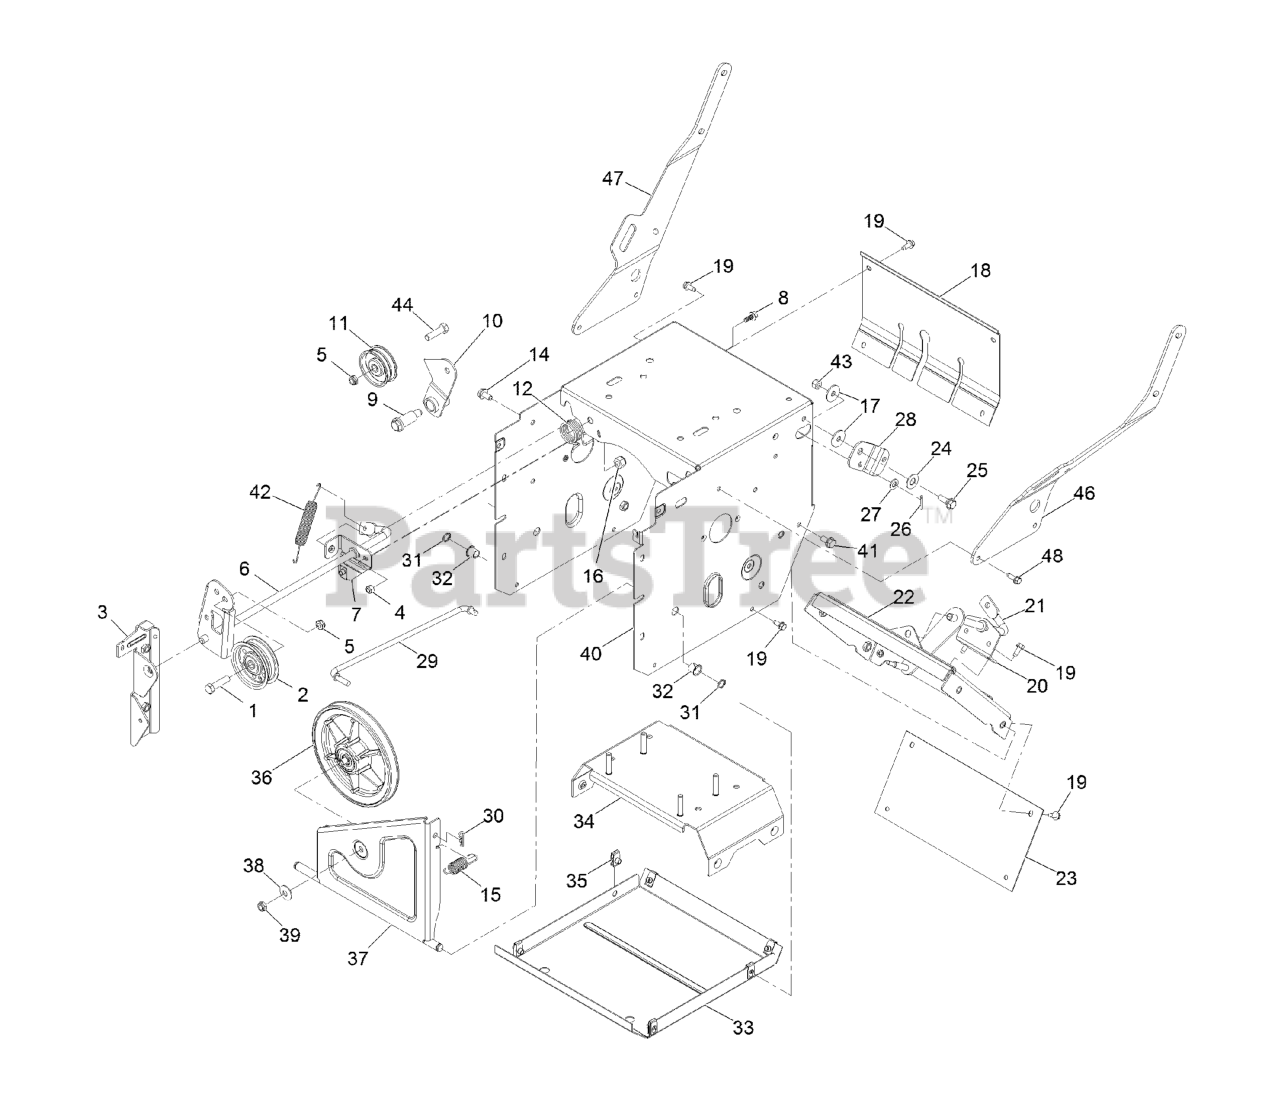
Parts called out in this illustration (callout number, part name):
1	SCREW-HH
2	PULLEY-IDLER
3	BRACKET-IMPELLER, IDLER
4	NUT-LOCK, NI
6	IMPELLER CLUTCH ASM
7	BRACKET-IMPELLER, CLUTCH
8	SCREW-HHF
9	BOLT-SHOULDER
10	ARM-IDLER, TRACTION
11	PULLEY-IDLER
12	SPRING-TORSION
14	SCREW-HHF
15	SPRING-EXTENSION
16	NUT-LOCK, NI
17	WASHER-PIVOT
18	COVER-UPPER
19	SCREW-HWH
20	BRACKET-SHIFT, ROD
21	TRACTION LEVER ASM
22	SHIFT PLATE ASM
23	COVER-LOWER
25	SCREW-SHOULDER
26	PIN-COTTER
27	WASHER-PLAIN
28	BELLCRANK
29	LINK-SPEED, CONTROL
31	RING-RETAINING
32	BUSHING-NYLINER
33	PAN-BOTTOM
34	BRACE-FRAME
36	PULLEY-TRACTION ASM
37	BRACKET-WHEEL, FRICTION
38	WASHER-BELLEVILLE
39	NUT-HEX
40	TRACTION FRAME ASM
41	SCREW-HWHTF
42	SPRING-EXTENSION
43	NUT-LOCK, NI
44	SCREW-HH
46	BRACE-HANDLE, LH
47	BRACE-HANDLE, RH
48	SCREW-HWH, THREAD ROLL
